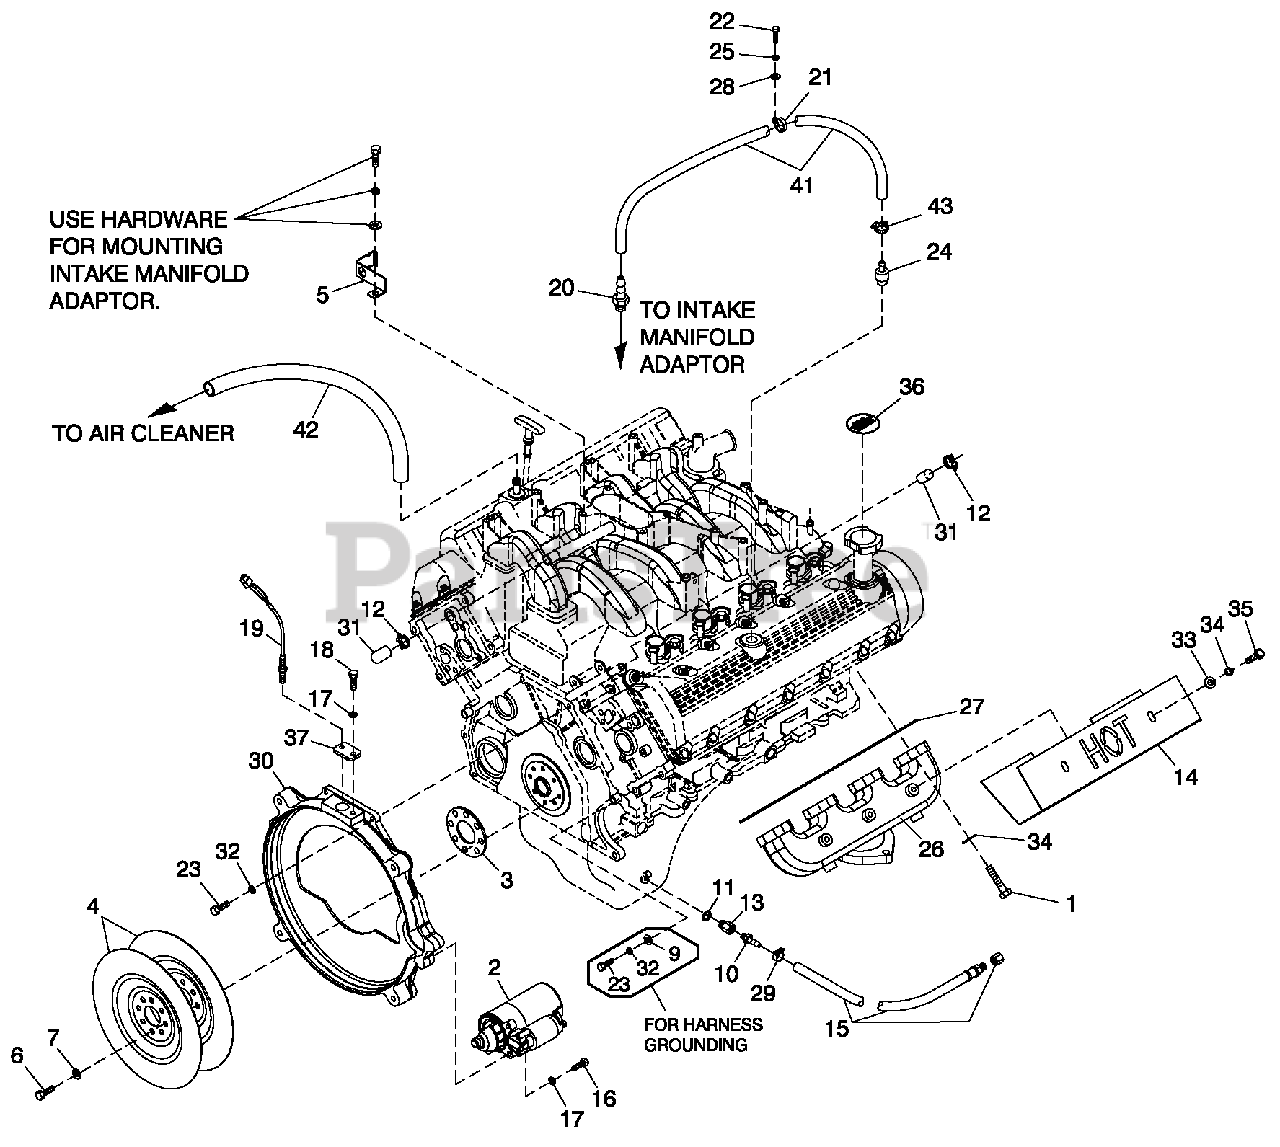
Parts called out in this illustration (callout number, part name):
1	SCREW SHCM8-1.25X 35 SS
2	STARTER MOTOR 12V
3	SPACER FLEXPLATE 5.4L/6.8L (1800 RPM ONLY)
4	FLEX PLATE 2 POLE 5.4L/6.8L (1800 RPM UNITS ONLY)
5	BRACKET, SIGNAL CONDITIONER
6	SCREW HHC M10-1.0 X 25 G10.9
7	WASHER FLAT .43X1.00
9	WASHER FLAT 3/8-M10 ZINC
10	BARBED STR 3/8 NPT X 3/8
11	WASHER NYLON .565
12	CLAMP HOSE #10 .56-1.06
13	ADAPTER M14-1.50X 3/8 NPT
14	HEAT SHLD EXHAUST MANIFOLD
15	HOSE DRAIN ASSY 28"
16	SCREW SHC M8-1.25 X 30 G12.9
17	WASHER LOCK M8-5/16
18	SCREW HHC M8-1.25X20 G8.8
19	ASSY MAGPICKUP (3/8-24 MALE)
20	BARBED STR 1/2 NPT X 5/8
21	CLAMP VINYL .75X.343Z
22	SCREW HHC M6-1.0X 16 G8.8
23	SCREW SHC M10-1.5 X 55 G12.9
24	VALVE PCV G3
25	WASHER LOCK M6-1/4
26	MACHINED MANIFOLD EXHAUST 5.4L
27	GASKET EXHAUST MANIFOLD
28	WASHER FLAT 1/4-M6 ZINC
29	HOSE CLAMP BAND 5/8"
30	ENGINE ADAPTER 5.4L/6.8L
31	CAP HOSE
32	WASHER LOCK M10
33	WASHER FLAT M8 SS
34	WASHER LOCK M8 SSTL
35	SCREW HHC 5/16-18 X 1/2 SSTL
36	DECAL REFER TO OWNERS MANUAL
37	PLATE MAG PICK-UP ADAPTOR
41	HOSE 3/8 ID SINGLE BRAID (15" LG)
42	HOSE 3/4 ID SAE-30R2
43	CLAMP HOSE #5 .5.62-.62
